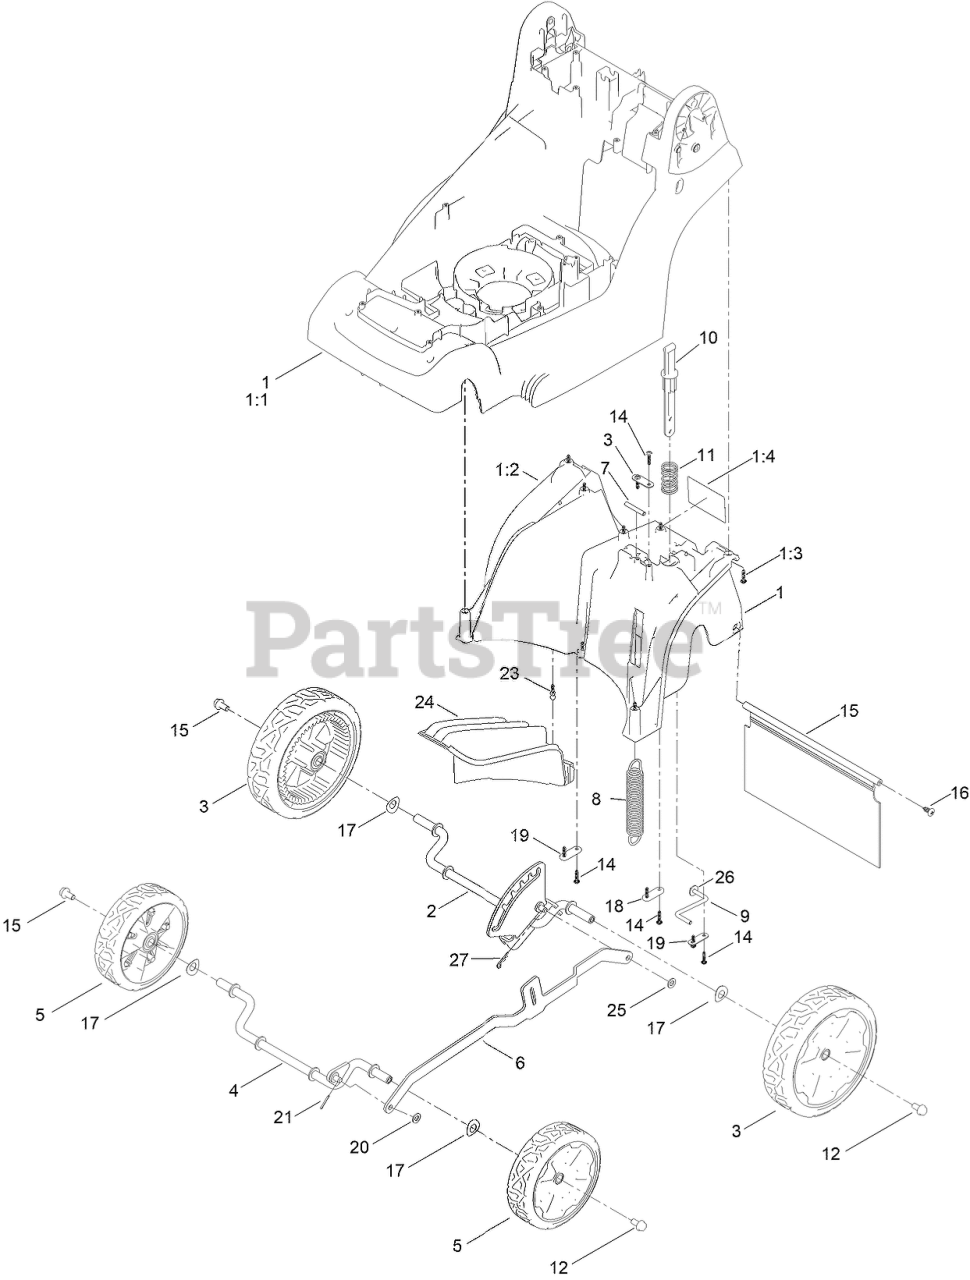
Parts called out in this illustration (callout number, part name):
1	DECK, GLUED (36)
1:1	DECK-36CM
1:2	36CM 4 WHEEL REAR CHASSIS MOULDING
1:3	SCREW, T20
1:4	DECAL - SAFETY
2	REAR AXLE FRAME, ASSY, WHEEL
3	WHEEL-REAR ASSEMBLY
4	FRONT AXLE, ASSEMBLY
5	WHEEL-TORO FRONT ASSEMBLY
6	CON-ROD, 4 WHEEL
7	BAR, SPRING MOUNT
8	HOC SPRING, 4 WHEEL
9	HOC WIRE
10	HOC BUTTON PLUNGER
11	SPRING, HOC BUTTON
12	BOLT, M8 X 1.25, 16MM
15	SHIELD-TRAILING, 36CM
16	SCREW-PTH
17	WAVE WASHER, FRONT WHEELS
18	AXLE PLATE
19	AXLE PLATE, SMALL
20	WASHER-PLAIN
21	COTTER PIN
23	PIN, RETAINING, MULCH PLUG
24	MULCH PLUG
25	WASHER
26	WASHER
27	COTTER PIN
